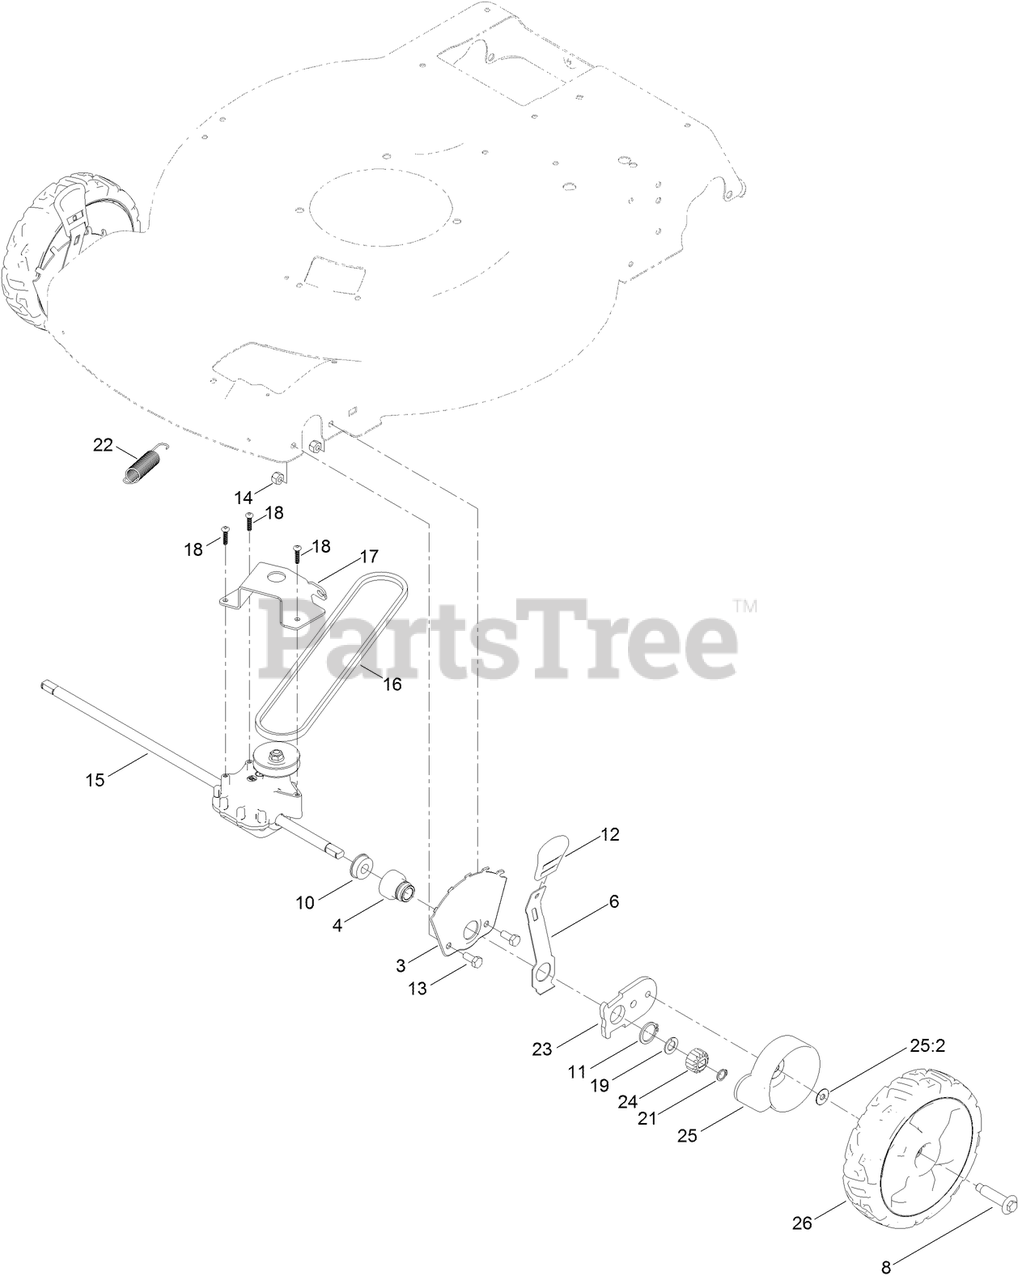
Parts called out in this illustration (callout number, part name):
3	PLATE-HOC, FRONT
4	RETAINER-BEARING, HOC
6	Arm-Spring
8	BOLT-SHOULDER
10	BEARING-BALL
11	RING-RETAINING
12	KNOB-HOC
13	SCREW-HH
14	NUT-LOCK, NI
15	TRANSMISSION
16	V-BELT
17	BRACKET-TRANSMISSION
18	SCREW-PLASTITE
19	WASHER-THRUST
21	RING-RETAINING
22	SPRING-EXTENSION
23	ARM-PIVOT, FRONT
24	GEAR-PINION, 15T
25	GEAR COVER ASM
25:2	WASHER-STEPPED
26	WHEEL GEAR ASM, 8IN
